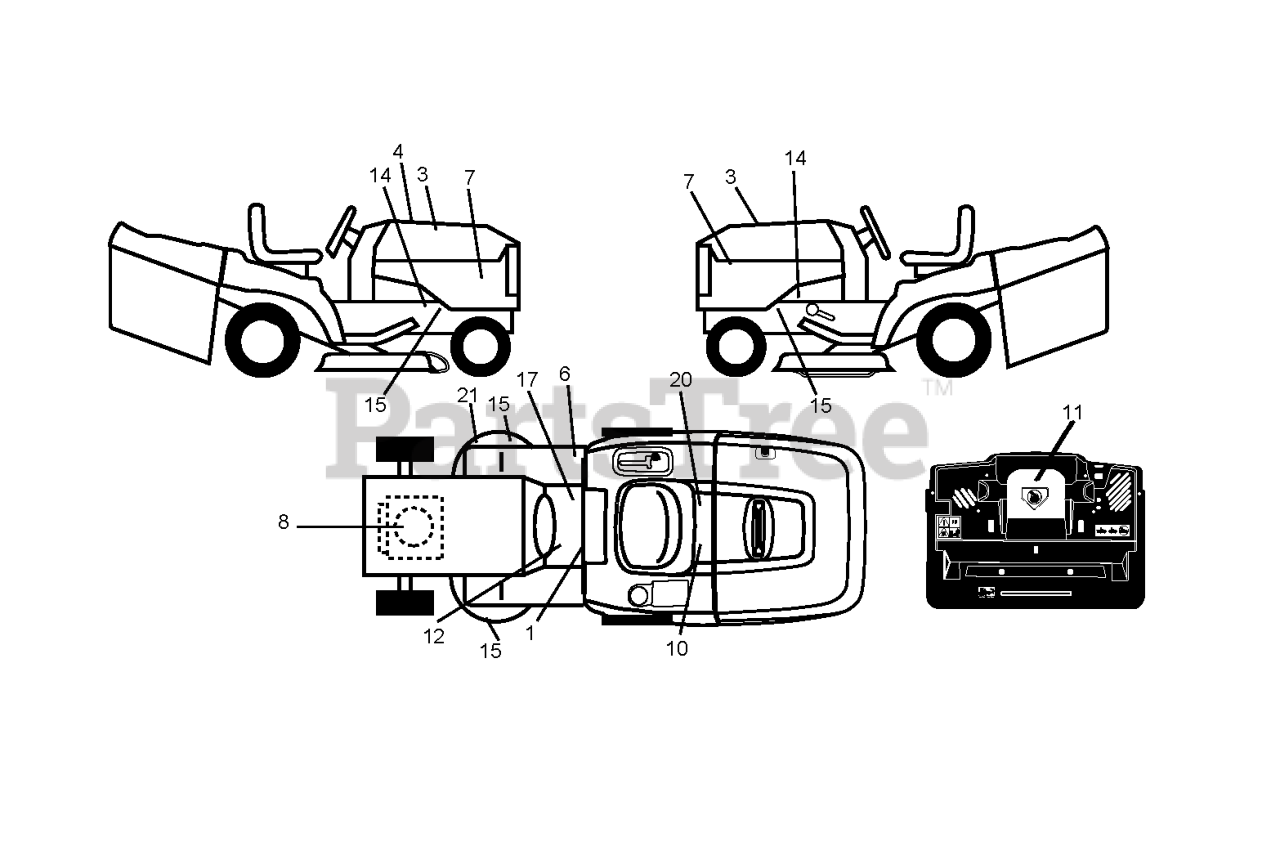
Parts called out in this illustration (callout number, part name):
1	LABEL
3	DECAL.HOOD.NAMELOGO.HUSQ
6	Decal, Fender 100 DB/CE
8	DECAL
10	DECAL BTRY SYMBOLS
11	DECAL.INTERNATIONL.CUTFINGER
12	DECAL
17	DECAL PARK BRAKE
20	DECAL.BYPASS.FENDER.CRD.LT.YT
